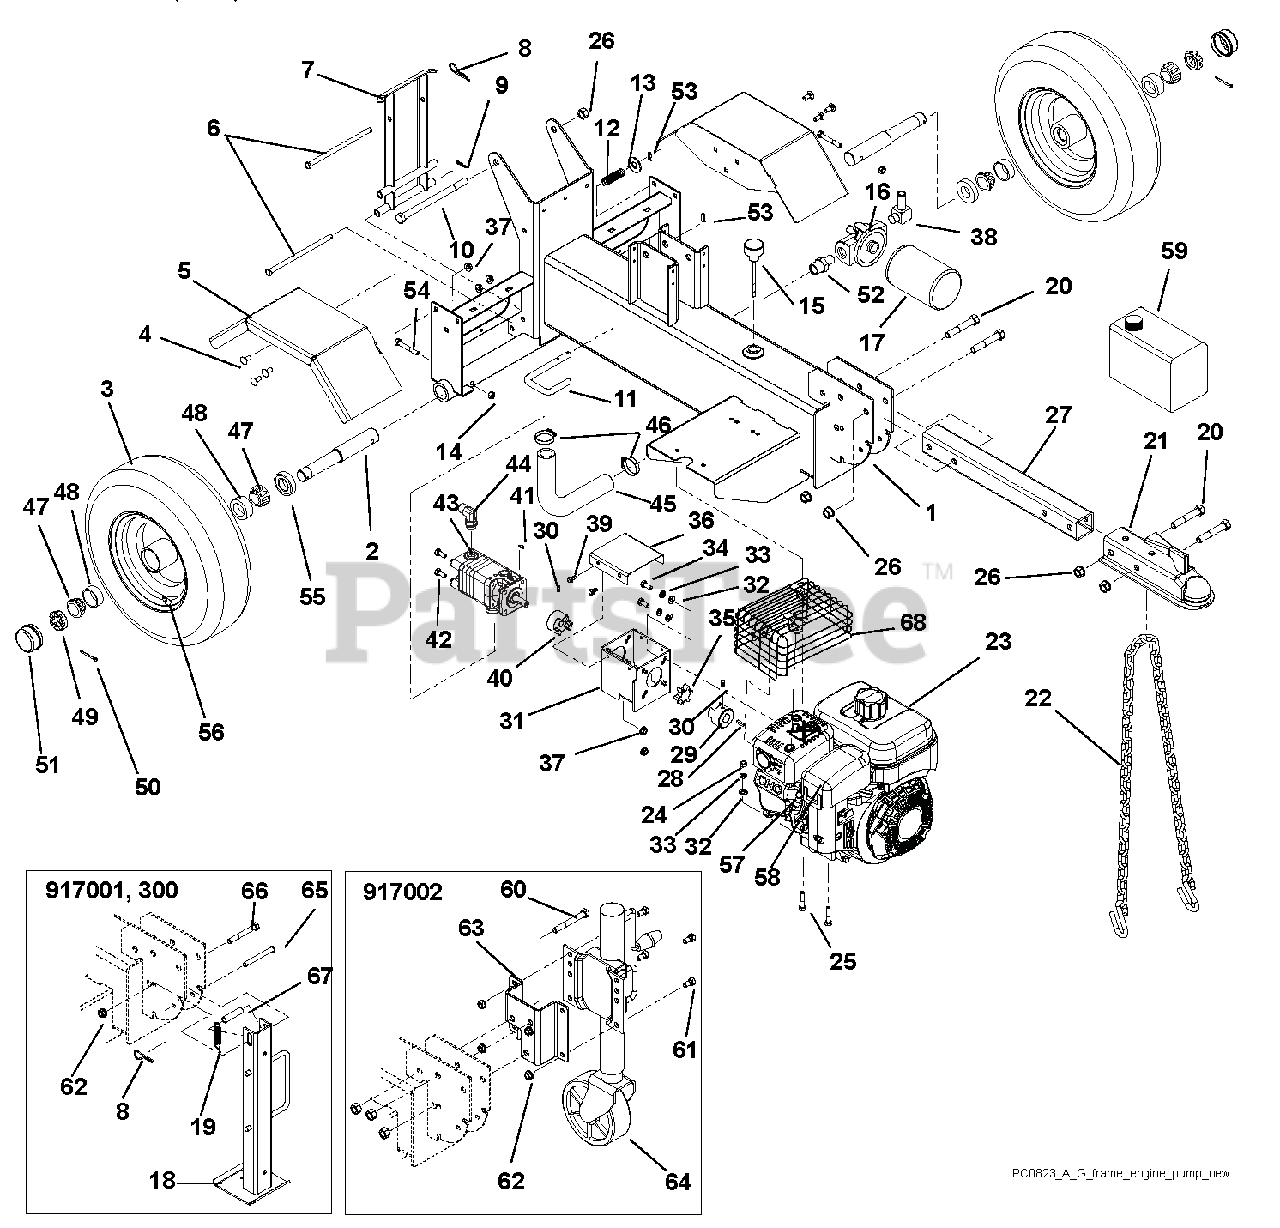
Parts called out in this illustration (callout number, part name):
1	CHASSIS,SPLITTER W/SAFTY DECAL
2	AXLE, SPLITTER
3	WHEEL, SPLITTER
4	@BLT-RDHDSQNK .31-18X.75 G5YZ
5	WLDMT, FENDER
6	PIN, LOCK
7	REAR STAND W/DECALS (ARIENS)
8	HAIRPIN, #7 CLIP .094X2.31 YWZ
9	PIN-HAIR, ENDRIES #25 YWZC
10	@BLT-HEX .50-13X7.50 GR5 YWZC
11	LOCK, BEAM
12	SPRG, COMP .058X.65X2.13 WLD15
13	@WSHR-FL-STL.563X1.38X.109YWZC
14	@NUT-LK-CTR .31-18 YWZC
15	BREATHER, DIPSTICK
16	HEAD,FILTER-3/4 NPT BYPASS
17	FILTER,OIL-W/BYPASS
18	WLDMT, JACK STAND
19	SPRG, TENSION .063X.625X2.50
20	@BLT-HEX .50-13X3.00 GR5 YWZC
21	HITCH, BALL-2"
22	CHAIN, SAFETY
23	ENGINE,SUBARU 6HP SP170 (CARB)
24	@NUT-HEX .31-18 YWZC
25	@BLT-HEX .31-18X1.50 GR5 YWZC
26	@NUT-LK-CTR .50-13 YWZC
27	HITCH BAR W/DECALS
28	KEY-SQ .188X.75X.188
29	HUB,DRIVE COUPLING 3/4"
30	SCR-SET .25-20X.38 SKHCUPNL OH
31	WLDMT, PUMP MOUNT BRKT
32	@WSHR-FL-STL.344X.688X.065YWZC
33	WSHR-LK .312X.097 HVY YWZC
34	BLT-HEX .31-24X.75 YWZC GR5
35	SPIDER,URETHANE
36	COVER W/DECALS
37	@NUT-LK-TOP-FLG .31-18 YWZC
38	FTG,HYD 4501-10-12-FG
39	SCR-TAP .25-20X.50 HWH TR YWZ
40	HUB,DRIVE COUPLING 1/2"
41	KEY-WDRF .125X.50X.20 (HRDEND)
42	@BLT-HEX .31-18X.75 GR5 YWZC
43	PUMP,SPLITTER-11 GPM
44	FTG,HYD 6801-8-8
45	HOSE,HYD SUCTION 16G4H X 13.5
46	CLAMP-HOSE 1.50X.81X1.42
47	BRG, CONE W/ GREASE
48	BRG-CUP1.980X.420
49	NUT-SL 1.0-14
50	@PIN-CTR .15X1.50 YWZC
51	CAP,DUST
52	FTG,HYD 5404-12-12
53	CLIP, SPRING
54	@BLT-HEX .31-18X2.25 GR5 YWZC
56	VALVE STEM ASS'Y
57	SPARK PLUG,SP-170
58	FILTER,SP-170 SPONGE/ROBIN
59	OIL, 2.5 GAL HYD ISO GRADE 32
60	@BLT-HEX .50-13X3.25 GR5 YWZC
61	@BLT-HEX .38-16X.75 GR5 YWZC
62	@NUT-LK-TOP-FLG .38-16 YWZC
63	BRACKET, MOUNTING
64	STAND, JACK-W/WHEEL
65	PIN-CLEV .371X3.25 YWZC
66	@BLT-HEX .38-16X3.00 GR5 YWZC
67	SPCR, WHEEL .385X.500X2.00
68	GUARD,MUFFLER,SUB 20A-37303-11
